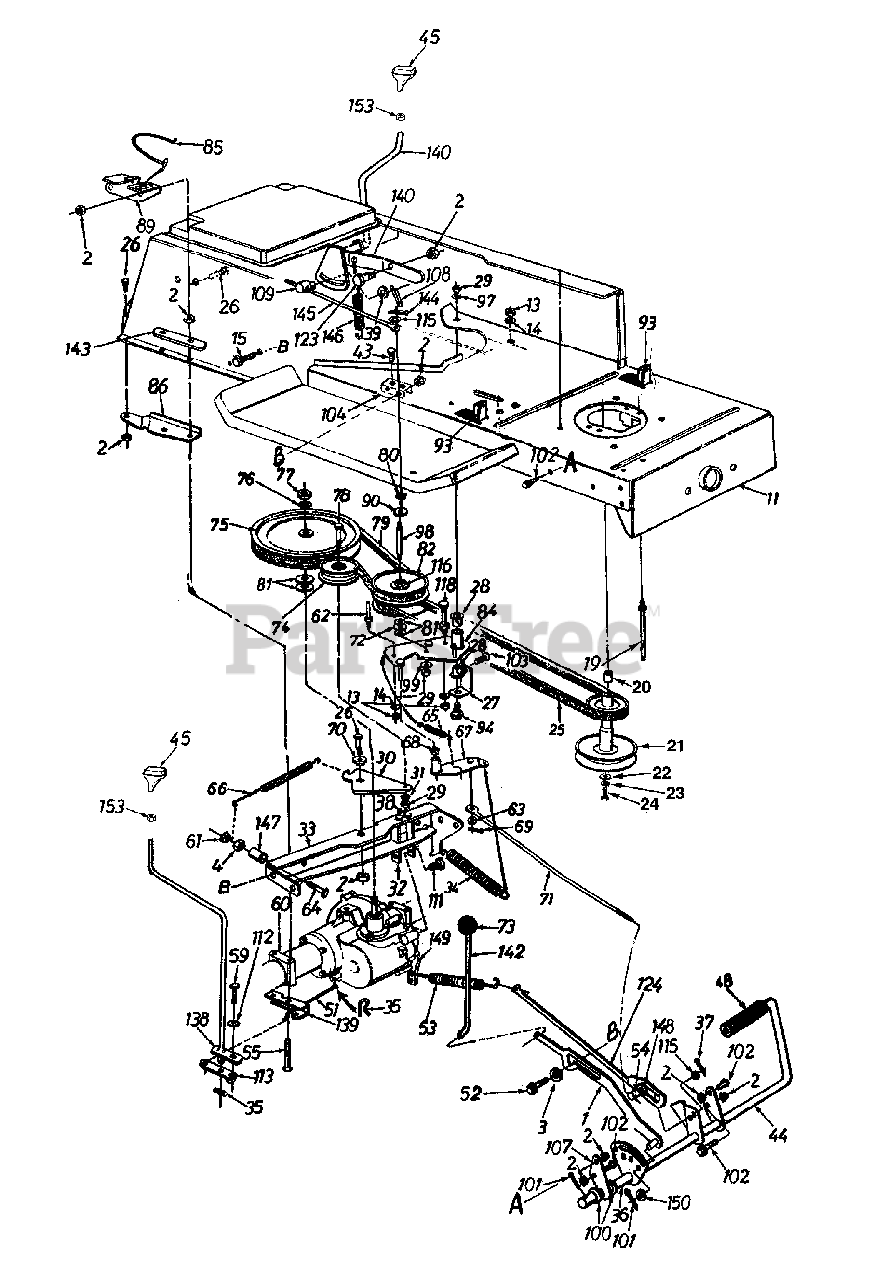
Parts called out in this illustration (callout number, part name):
1	Parking Brake Lockout Brkt. Ass'y.
2	Hex Sems Nut 5/16-18 Thd.
3	Fl-Wash. .442" I.D. x 1.38" O.D.
4	Hex Nut 5/16-24 Thd.
13	Hex Nut 1/4-20 Thd.
14	L-Wash. 1/4" I.D.
15	Hex TT-Tap Scr. 5/16-18 x .62"
19	Belt Guard Pin
20	Spacer 1" I.D.
21	Engine Pulley
22	Shld. Spacer .445" I.D.
23	L-Wash. 7/16" I.D.
24	Hex Bolt 7/16-20 x 1 1/4" Lg.
25	Variable Speed Belt
26	Hex Bolt 5/16-18 x .75" Lg.
27	Bearing Shaft Bracket Ass'y.
28	Flanged Nyliner Brg. .63" I.D. x .6" Lg.
29	Hex Nut 3/8-24 Thd.
30	Idler Bracket
31	L-Wash. 3/8" I.D.
35	Inter. Cotter Pin
36	Spacer .63" I.D.
37	Cotter Pin 1/8" Dia. x 1.0" Lg.
38	Self-Tap Scr. 5/16-18 x .5" Lg.
39	FL-Wash. .51" I.D. x .75"
43	Hex Wash. Hd. S-Tap Scr.1/4-20 x .50" Lg.
48	Foot Pad
51	Shift Lever Rod
52	Shld. Bolt .437"
53	Ext. Spring 3.6"
54	Ferrule
55	Hex Bolt 5/16-18 x 3.25"
59	Hex Bolt 1/4-28 x .62" Lg.
60	Transaxle Complete
61	Hex L-Nut 1/4-20 Thd.
62	Belt Guard Pin 1/4-20 Thd.
63	Fl-Wash. .34" I.D. x .68" O.D.
64	Hex Wash. TT-Tap Scr. 1/4-20 x 1.75"
65	Ext. Spring 2.59" Lg.
66	Ext. Spring .5" O.D. x 4.35"
68	Flanged Bearing
69	Cotter Pin 3/32" Dia.
70	Shoulder Spacer .27" Lg.
71	Speed Control Link
72	Truss Bearing .56 Dia. x 1.25"
73	Ball Knob
74	Fl-Idler Pulley 3.25" x .75"
75	"V"-Pulley
76	L-Wash. 1/2" I.D.
77	Hex Jam Nut 1/2-20 Thd.
78	Hex Bolt 3/8-24 x 1.75" Lg.
79	Variable Speed Belt
80	Snap Ring .56" Dia.
81	Fl-Wash. .56" I.D. x 1.0" O.D.
82	Variable Speed Pulley Ass'y. 5" O.D.
90	Teflon Washer .565" I.D.
93	Safety Switch (Clutch)
94	Shld. Bolt 3/8-24 x 3.12" Lg.
97	Bell-Wash. .38" I.D. x .88"
98	Shaft
99	Bell-Wash. .39" I.D. x 1.12"
100	Fl-Wash. .64" I.D. x .94"
101	Cotter Pin 3/32" Dia. x 1" Lg.
102	Hex Wash. Hd. Scr. 5/16-18x .62" Lg.
103	Hex Wash. Hd. AB-Tap Scr. .75" Lg.
104	Bracket
109	Ferrule
111	Hex Wash. Tap Scr.
112	Bell-Wash. .265" I.D. x .75"
113	Shift Lever Link Ass'y.
115	Fl-Wash. .385" I.D. x .62"
116	Needle Brgs.
118	Hex Bolt 1/4-20 x 3.5" Lg.
123	Shld. Bolt .437" Dia. x .162"
124	Brake Rod Ass'y.
138	Shift Lever Ass'y.
139	Shift Lever Support Brkt.
140	Speed Selector Lever Ass'y.
142	Brake Lockout Rod
144	Cotter Pin 1/8" x 3/4" Lg.
145	Speed Selector Rod
146	Ext. Spring 3.97" Lg.
147	Spacer .326" I.D. x .47"
148	Fl-Wash. 5/8" I.D. x 1.25"
149	Actuating Arm
150	Fl-Wash. .385" I.D. x .62" O.D.
153	Hex Jam Nut 3/8-16 Thd.
